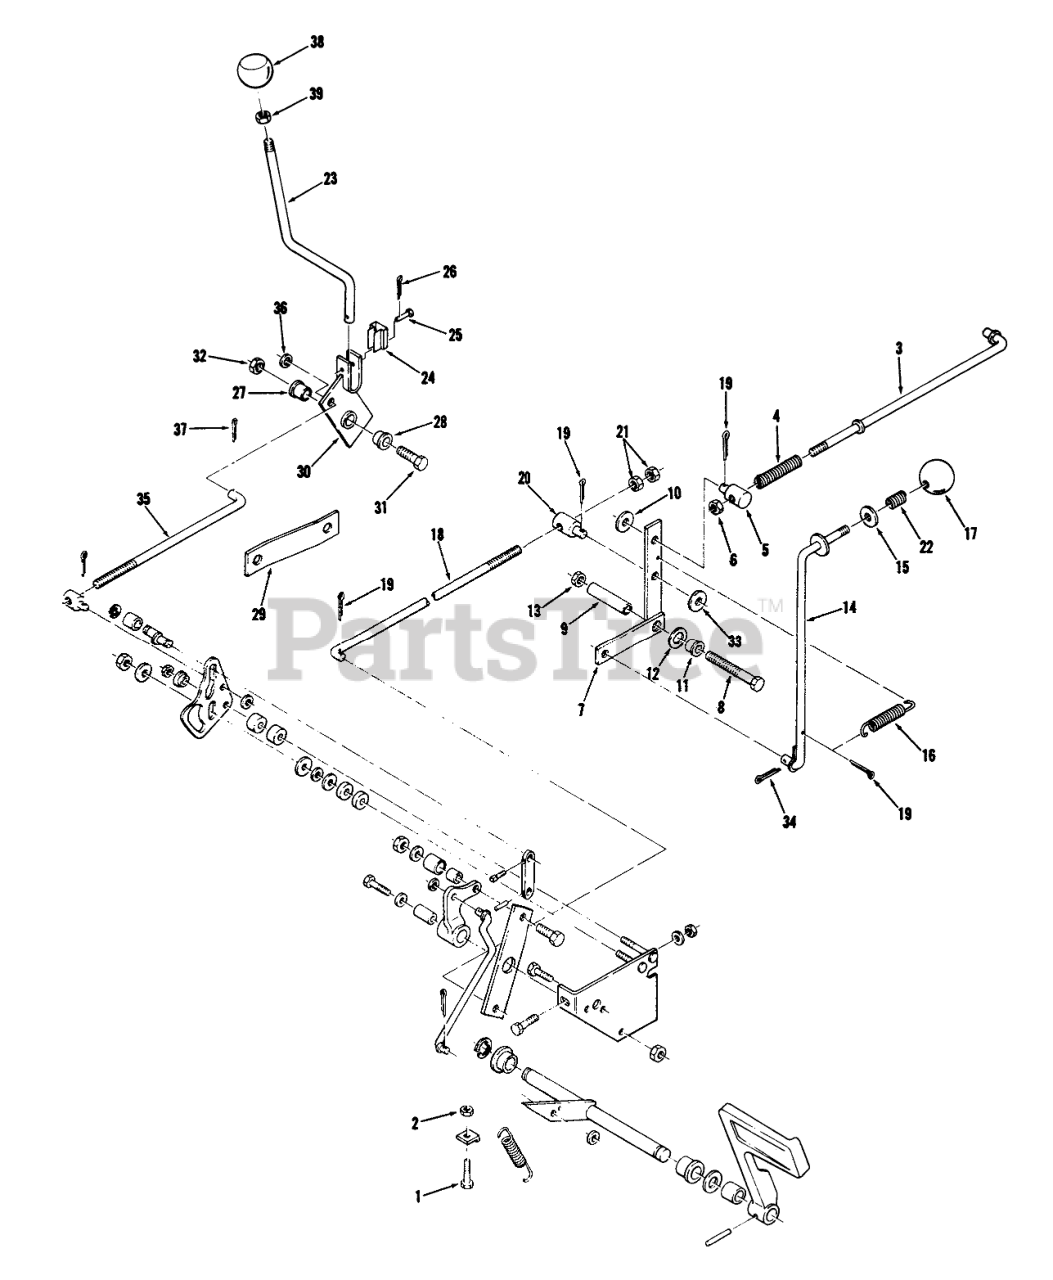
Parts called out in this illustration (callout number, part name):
1	Bolt
2	NUT
3	Assy-Rod
4	Spring
5	TRUNNION-LIFT
6	NUT
7	Assy-Arm Brake
8	HHCS
9	Spacer
10	Washer
11	FLANGED BUSHING
12	Washer
13	NUT
14	Assy-Brake Rod
15	Washer-Nylon
16	SPRING
17	SHIFT KNOB
18	Rod
19	Cotter Pin
20	TRUNNION-LIFT
21	Nut
22	SPRING-COMPRESSION
23	HANDLE
24	Spring
25	Clevis Pin
26	Cotter Pin
27	CAM-SPACER
28	FLANGED BUSHING
29	Brace
30	ASSY-PIVOT
31	Bolt
32	NUT
33	Washer
34	Cotter Pin
36	Washer
37	Cotter Pin
39	Jam Nut
